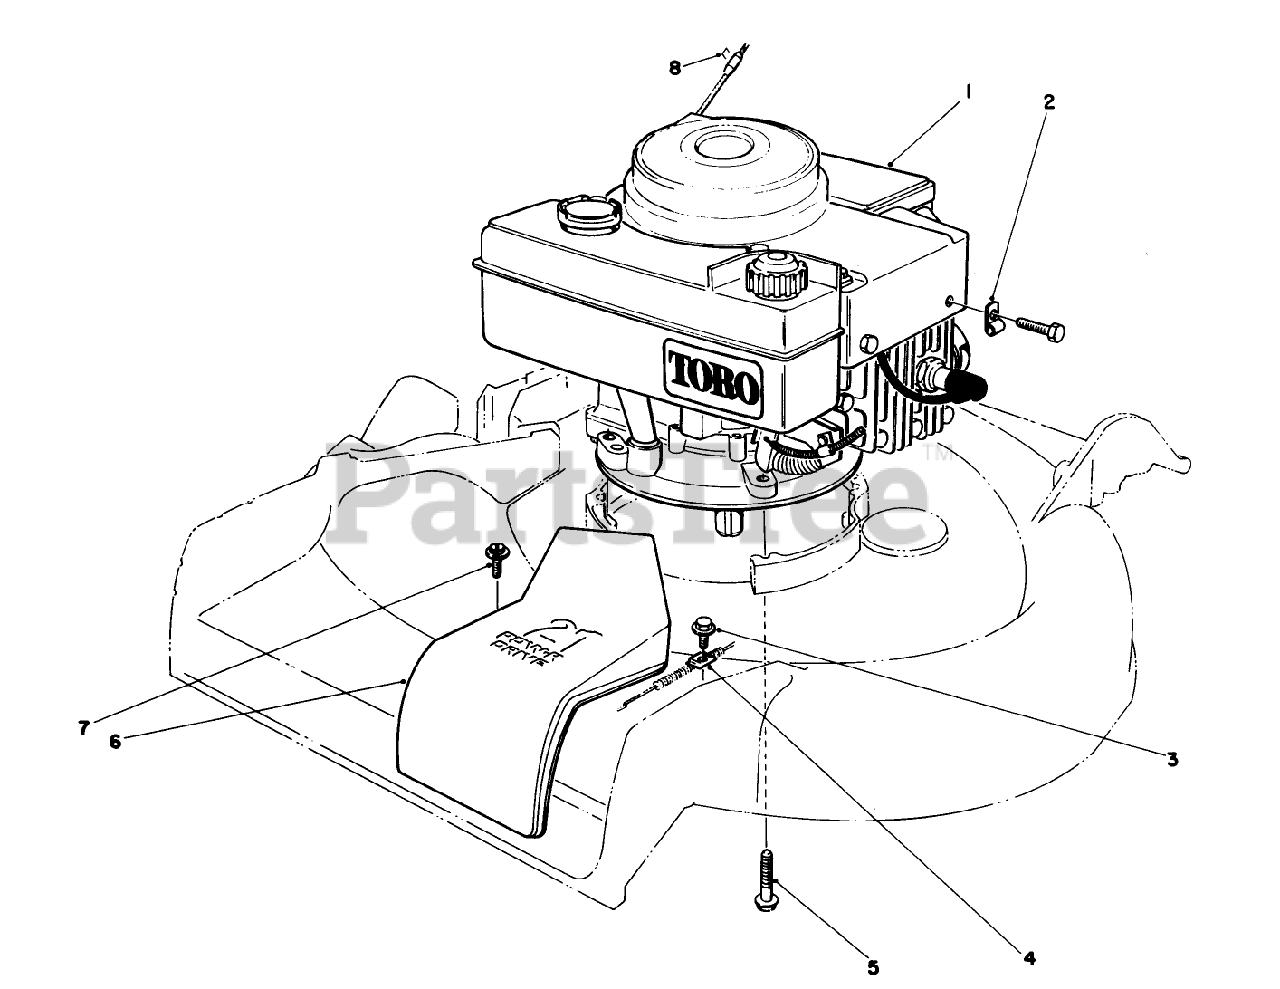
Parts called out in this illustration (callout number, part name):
1	Engine
3	SCREW-THD ROLL, HWH
4	CLAMP-CABLE
5	3/8-16 X 2-3/4 CAPSCR
6	BELT COVER 21" S D
7	SCREW
8	Staple
